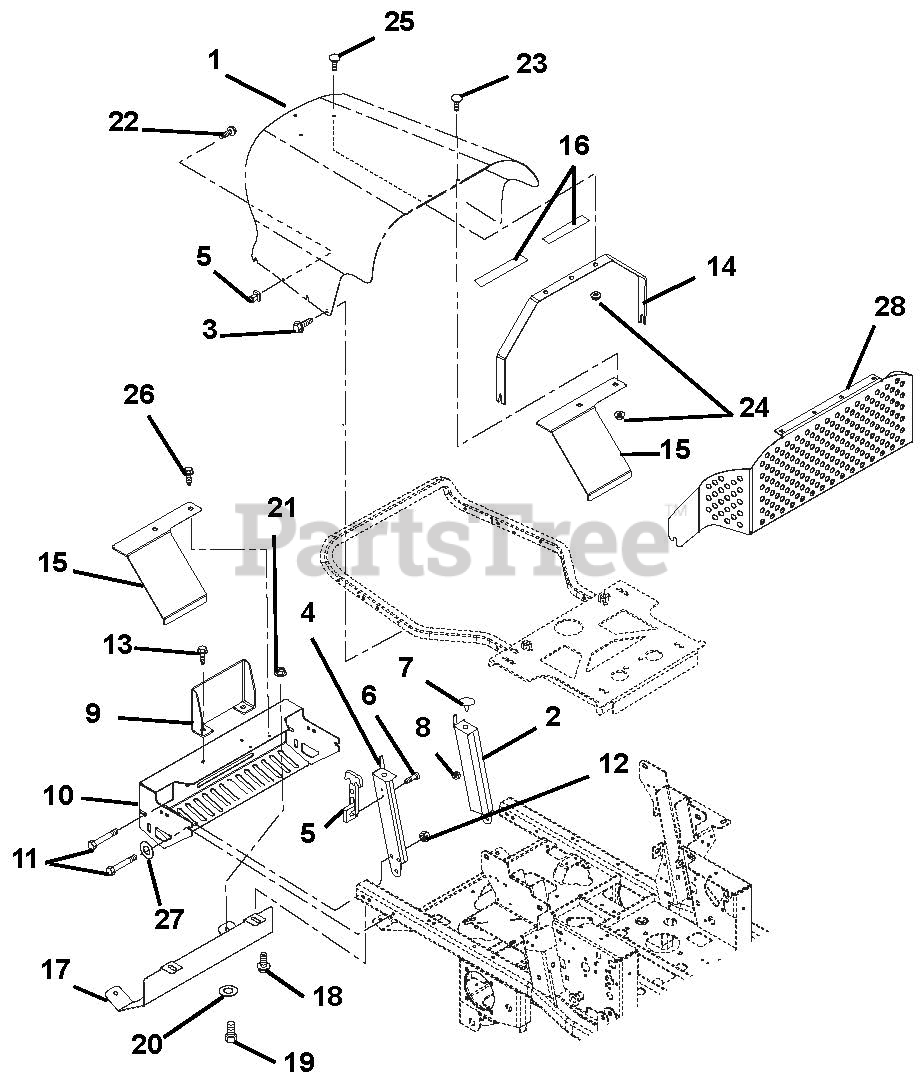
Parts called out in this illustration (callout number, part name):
2	Weldment, Hood Support, Left Hand
3	Screw, Tapping .38-16 x .75 Hex Washer Head
4	Weldment, Hood Support Right Hand
5	Latch, Rubber
6	Screw, Machine 10-24 x .50 Hex Washer Head
7	Button Bumper
8	Nut, Spin Lock Flange .312-18
9	Guard, Muffler
10	Bumper, Rear
11	Bolt, Hex .38-16 x 2.75 Grade 5
12	Nut, Locking Top Flange .38-16
13	Screw, Tapping .38-16 x .75 Hex Washer Head
14	Hood Support
15	Guard
16	VHB Tape 4941F
17	Heat Shield
18	Screw, Tapping .38-16 x .50 Hex Washer Head Thread Rolling YWZ
19	Bolt, Hex .38-16 x .75 Grade 5
20	Washer, Flat Steel .438 x1.00 x .083 YWZ
21	Nut, Locking Top Flange .38-16
22	Screw, Machine 10-24 x 1.50 Hex Washer Head
23	Bolt, Round Head Square Neck .25-20 x .50 Grade 5
24	Nut, Locking Top Flange .25-20
25	Bolt, Round Head Square Neck .25-20 x .75 Grade 5
26	Screw, Tapping .25-20 x .50 Hex Washer Head Thread
27	Washer, Flat Steel .406 x .812 x .065
28	Plenum, Hood
